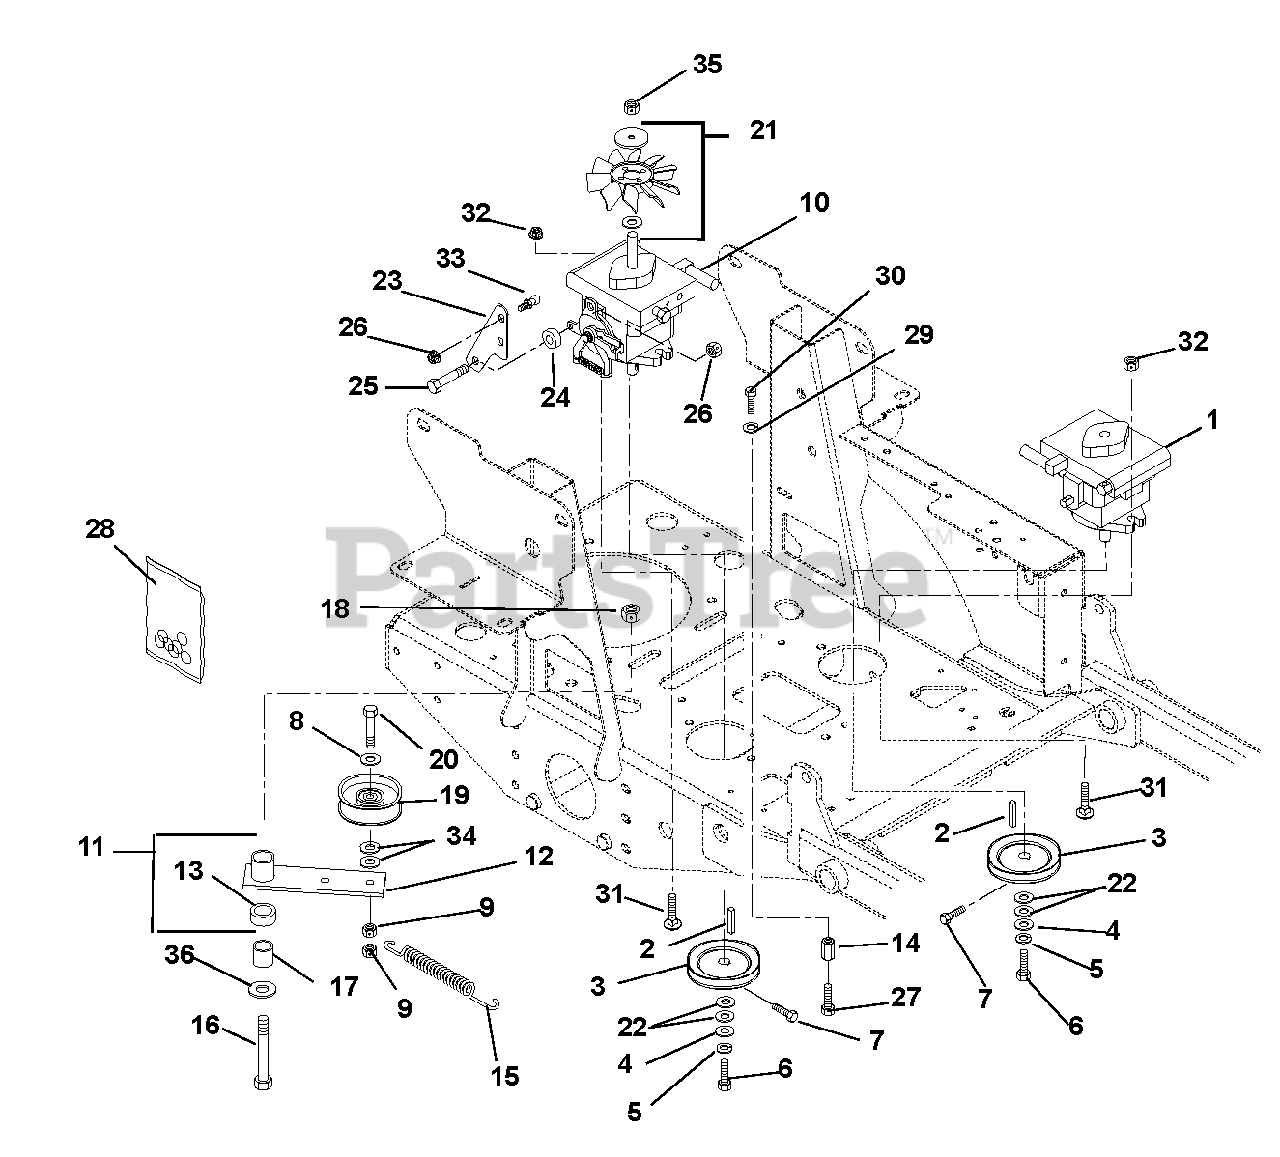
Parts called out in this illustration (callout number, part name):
1	Pump, Hydraulic BDP-10A Left Hand (page 14)
2	Key, Straight 5mm x 25mm x 5mm
3	Sheave 4.0 x .199
4	Washer, Flat Steel .281 x 1.00 x .063
5	Washer, Locking .25 x .062
6	Bolt, Hex M6 x 1.00 x 12 Epoxy 30
7	Bolt, Hex .25-20 x .50 Grade 5
8	Washer, Flat Steel .406 x .812 x .065
9	Nut, Nyloc Flange .38-16
10	Pump, Hydraulic BDP-10A Right Hand (page 15)
11	Assembly, Idler Arm Guard Drive (Includes 12 & 13)
12	Weldment, Idler Arm Ground Drive
13	Bearing, 1.00 x 1.12 x .75
14	Nut, Coupling .375-16 x 1.75
15	Spring, Extension
16	Bolt, Hex .50-13 x 3.50
17	Bushing, Spacer .505/.500 x .999/.996 x 2.05/2.03
18	Nut, Nyloc Flange .50-13
19	Idler, Flat 4.00 x .38 I.D.
20	Bolt, Hex .38-16 x 2.50
21	Fan, Cooling
22	Washer, Flat Steel .656 x 1.31 x .095
23	Bracket, Return to Neutral/Damper
24	Spacer .344 x 1.00 x .375
25	Bolt, Hex .31-18 x 1.25
26	Nut, Nyloc Flange .312-18
27	Bolt, Hex .38-16 x 1.50
28	Kit, Pump Seal (BDP-10A) (One kit required for each pump)
29	Washer, Locking .38 x .094
30	Bolt, Hex .38-16 x .75
31	Bolt, Round Head Square Neck .44-14 x 1.50
32	Nut, Nyloc Flange .44-14
33	Stud, Ball
34	Washer, Flat Steel .406 x 1.00 x .188
35	Nut, Center-Lock .31-24
36	Washer, Flat Steel .511 x 1.441 x .125
